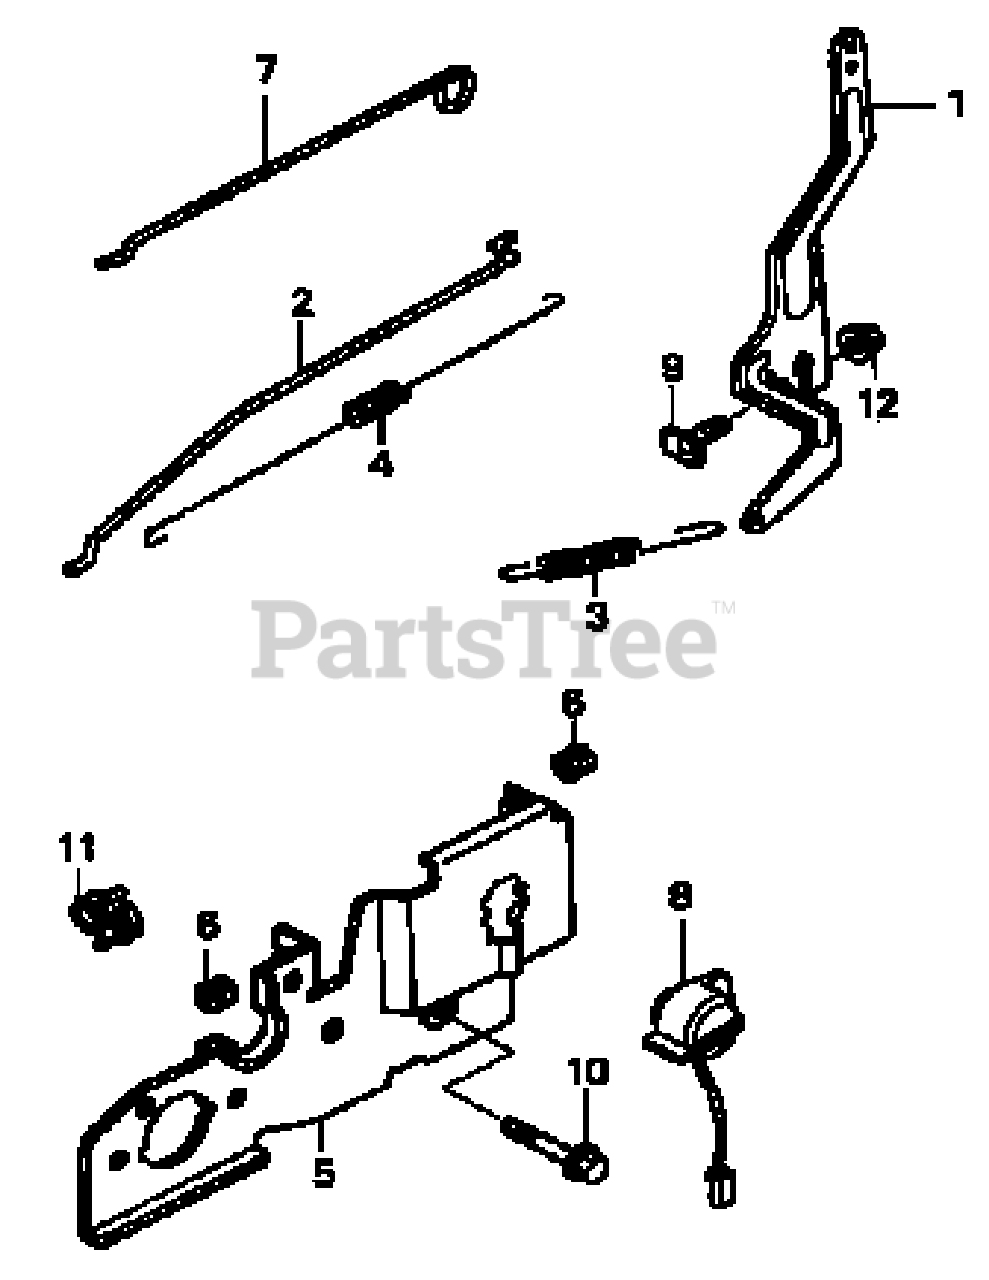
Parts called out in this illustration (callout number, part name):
1	Governor Arm
2	Governor Rod
3	Governor Spring
4	Throttle Return Spring
5	Control Base
6	Choke Rod Grommet
8	Engine Stop Switch Assy.
9	Governor Arm Bolt
10	Flange Bolt (6x45)
11	Cable Clip
12	Flange Nut (6mm)
